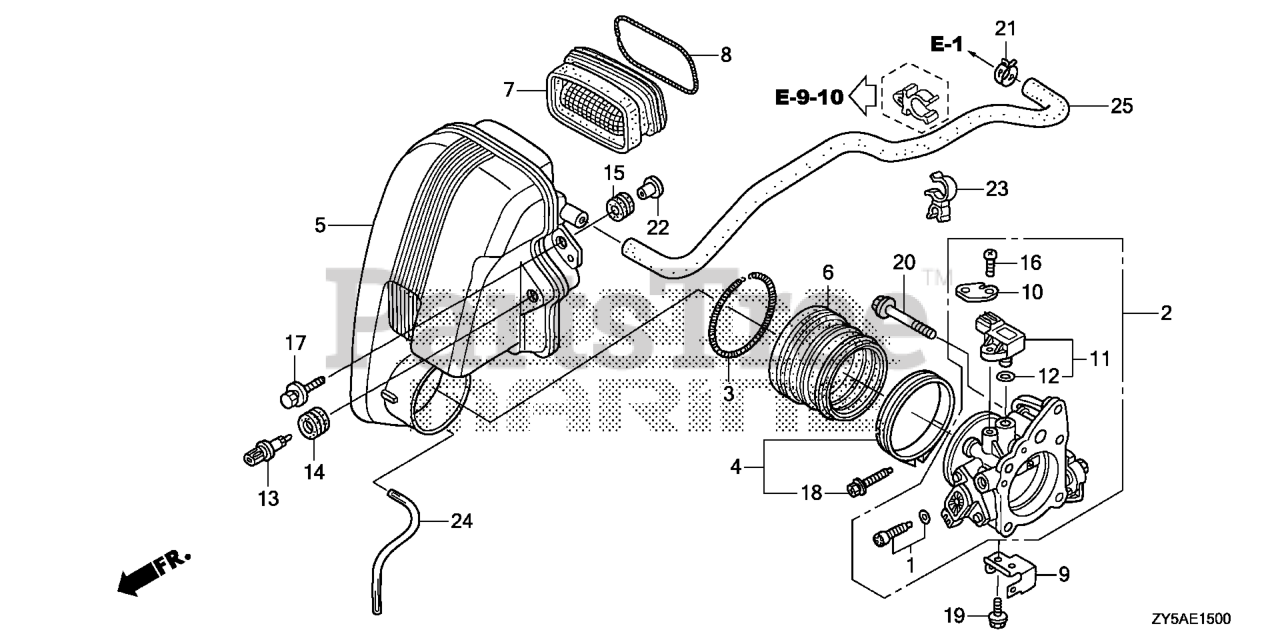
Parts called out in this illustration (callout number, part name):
2	BODY ASSY., THROTTLE
3	SPRING, AIR FLOW TUBE
4	BAND, AIR FLOW
5	CASE, MUFFLER
6	GROMMET, MUFFLER
7	GROMMET, MUFFLER DUCT
8	SPRING, MUFFLER DUCT GROMMET
9	BRACKET E, HARNESS CLIP
10	BRACKET, SENSOR WIRE
11	SENSOR ASSY., MAP
13	SENSOR ASSY., AIR TEMPERATURE (MATSUSHITA DENSHI)
14	GROMMET, TA SENSOR
15	GROMMET, CASE (LOWER)
16	SCREW, PAN (5X18)
17	BOLT-WASHER (6X25)
18	BOLT-WASHER (5X30)
19	BOLT, FLANGE (6X12)
20	BOLT, FLANGE (8X60)
21	CLAMP, TUBE (D17)
22	COLLAR, MODULE IGNITION CONTROL CASE (CDI)
23	CLAMP, FUEL HOSE
24	BULK HOSE, VINYL (4X7X8000) (95003-07(95003-07001-60M) (CARBURETOR NO.)
25	BULK HOSE, VACUUM (12X1000) (12X740)
